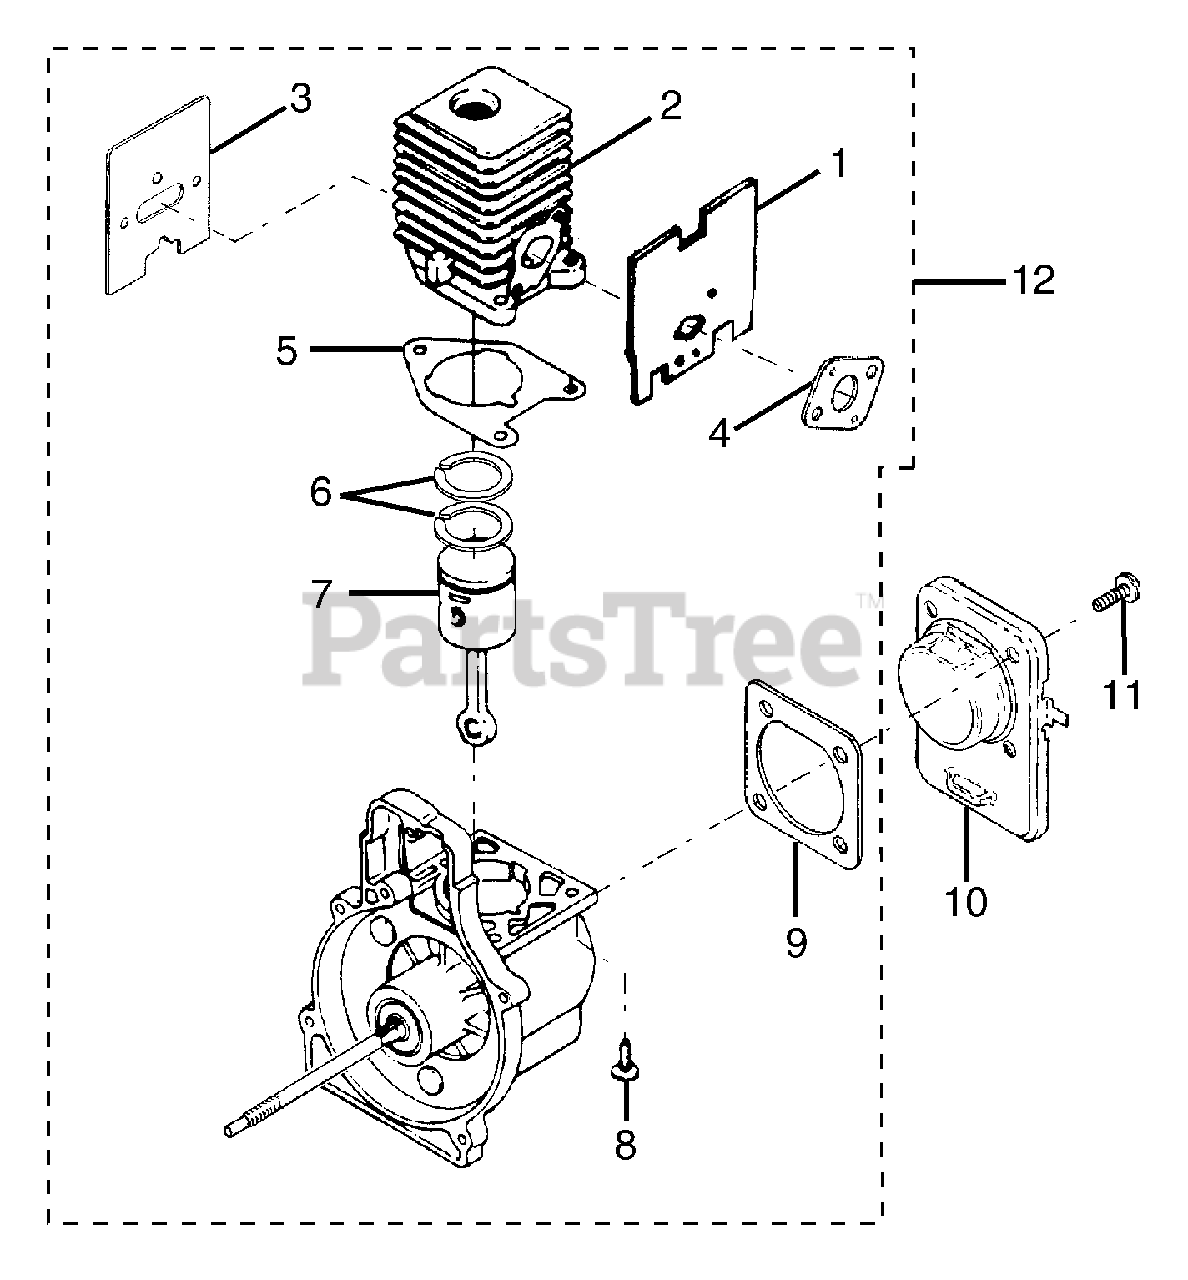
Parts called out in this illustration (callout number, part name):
1	HEAT DAM GASKET
2	CYLINDER
3	MUFFLER GASKET
4	CARBURETOR GASKET
5	CYLINDER GASKET
6	PISTON RING ( 1-5/16 in.)
7	PISTON ASSEMBLY KIT
8	SCREW (12-24 x .660 PAN TORX)
9	GASKET COVER, C/C
10	CRANKCASE COVER
11	PAN HEAD SCREW
12	SHORT BLOCK ASSEMBLY
